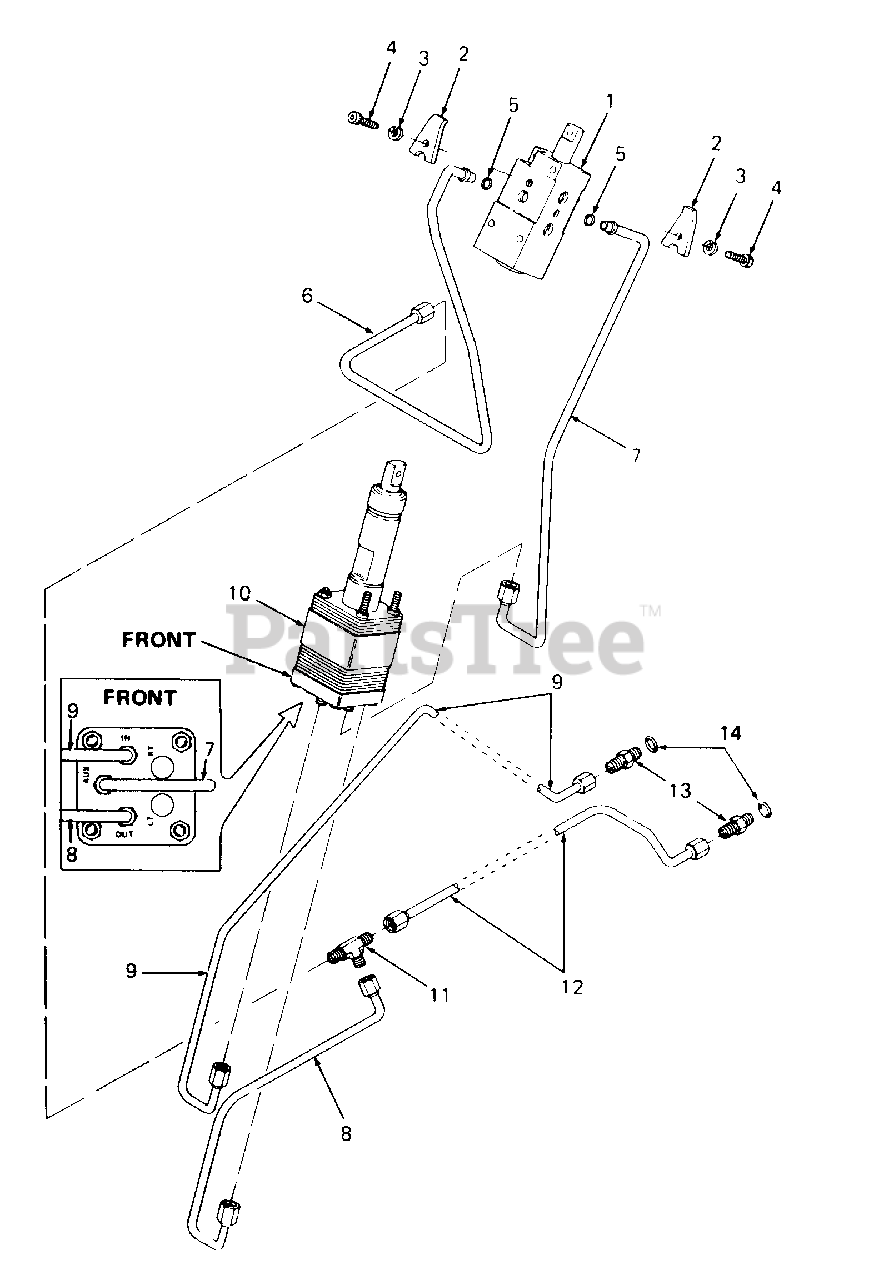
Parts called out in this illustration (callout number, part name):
1	Valve, Lift
2	Clamp, Single
3	Washer, Lock, 1/4
4	Screw, Socket Hd Cap, 1/4-20 X .62 Lg GR8
5	O-Ring, .301 X .070 Dia
6	Tube Assy,P.S Return-Upper.
7	Tube Assy, P S Aux
8	Tube Assy, P.S. Return
9	Tube Assy, P.S. Inlet
10	Power Steering Box w/Flat
11	T-Fitting
12	Tube Assy, P.S. Return - Lower
13	Connector, 37 Deg Tube
14	O-Ring, 3/8 OD Tube
